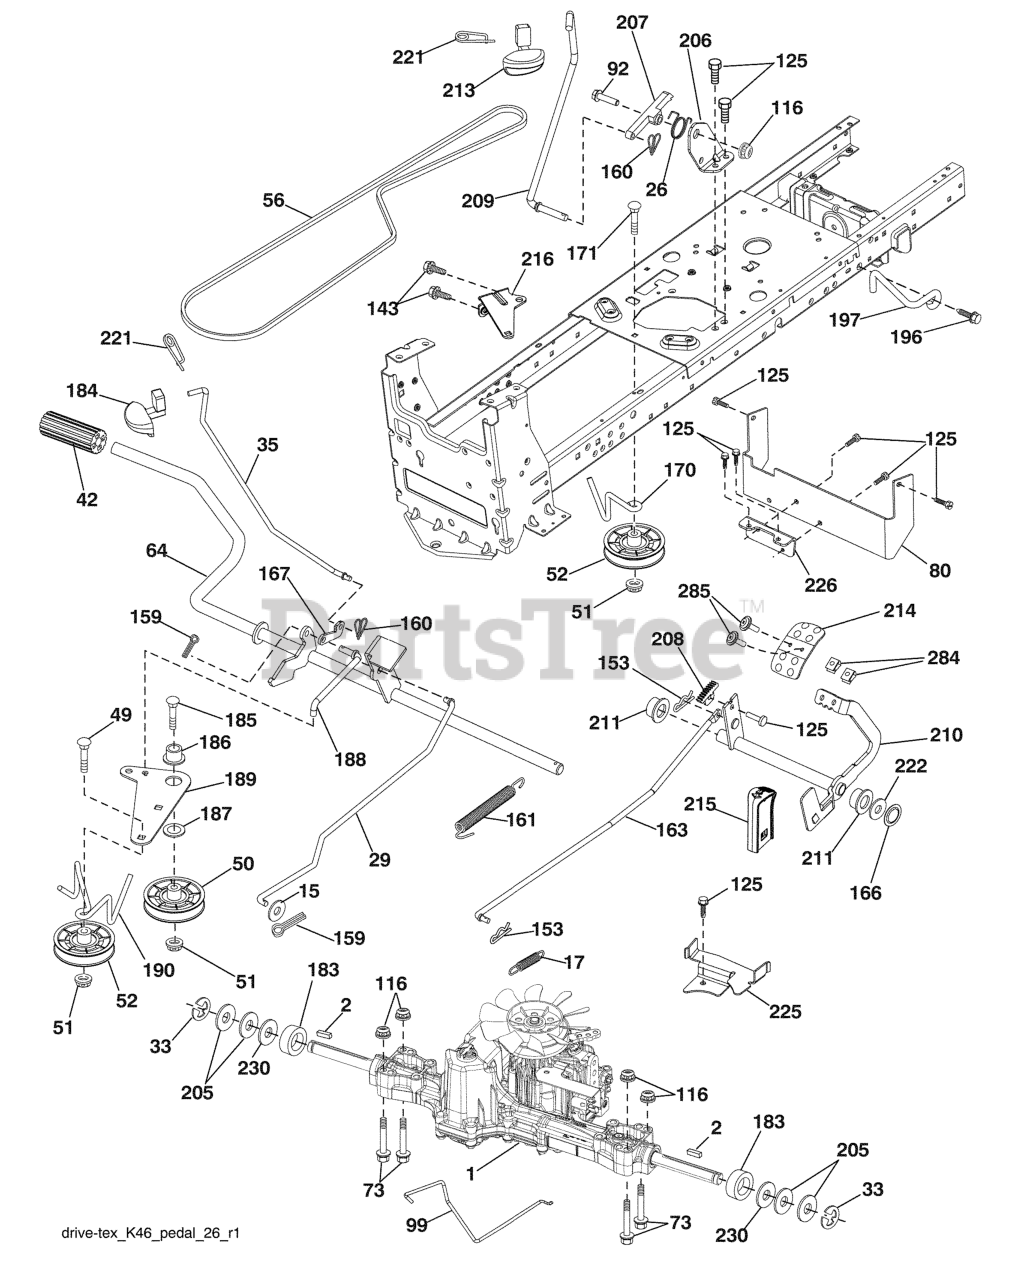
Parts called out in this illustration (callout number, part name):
1	TRANSAXLE, TUFFTORQ K46
2	SQUARE KEY
15	WASHER
17	SPRING.BRAKE.K46.GREEN
26	SPRING.RETURN.CRUISE
29	ROD.BRAKE.K46
35	ROD.BRAKE.PARKING.GT.H
42	PEDAL COVER T
50	IDLER.FLAT.910.OFFSET
51	NUT LOCK FLG 3/8-16 UNC
52	IDLER.V-GROOVE.910.OFFSET
56	V-BELT.MOWER.92.40.42/K46
64	SHAFT.ASM.PEDAL.BRK.CNTR
73	BOLT HEX 5/16-18 GR 5
80	STRAP TORQUE.ASM.K46/18"TEX
92	BOLT
99	ROD.SPRING.BYPASS.K46.LT.Z
116	NUT LOCK HEX FLANGE 5/16-18
125	SCREW
143	Screw 5/16-18 x 1/2
153	RETAINER M
159	COTTER PIN
160	RETAINER CLIP
161	SPRING, RETURN LT
163	ROD.CONTROL.PEDAL.K46
166	NUT.PUSH.625.2006
167	LATCH.BRAKE.SPRING
170	KEEPER.V-IDLER.CENTER.
171	BOLT
183	SPACER AXLE
184	HANDLE.PARKG.BRK.HUSQ X667
186	SPACER.RETAINER
187	WASHER 12/32X2X10GA
188	RP.LINK.CLUTCH.GROUND.DRIVE
189	BELLCRANK.GROUND.DRIVE.TEX.
190	KEEPER.BELLCRANK.DRIVE
196	SCREW 3/8-16X1
197	LINK.CLUTCH.ANIT-ROTAT
206	BRKT.MOUNT.LATCH.CRUIS
207	LATCH.CONTROL.CRUISE
208	GEAR.SECTOR.CONTROL.CR
209	ROD.CONTROL.CRUISE.GT.
210	ROCKER.ASM.PEDAL.CONTR
211	BEARING.NYLON
213	KNOB.CONTROL.CRUSIE.HU
214	PEDAL.FORWARD.HUSQVARNA.DEALER
215	PEDAL.REVERSE.TEX.GT.4
216	BRACKET.PULLEY.IDLER.W/TEX
221	RETAINER.SPRING.CLIP.H
222	WASHER 21/32 X 1-1/4 X 10 GA.
225	KEEPER.BELT.TRANSAXLE.K46
226	BRACKET.MOUNT.TORQUE.K46.TLT
230	WASHER.HARDENED
284	NUT.U-CHNL.1/4-20.550DP.350PNL
285	SCREW.PHD.1/4-20.BOX DRVE
